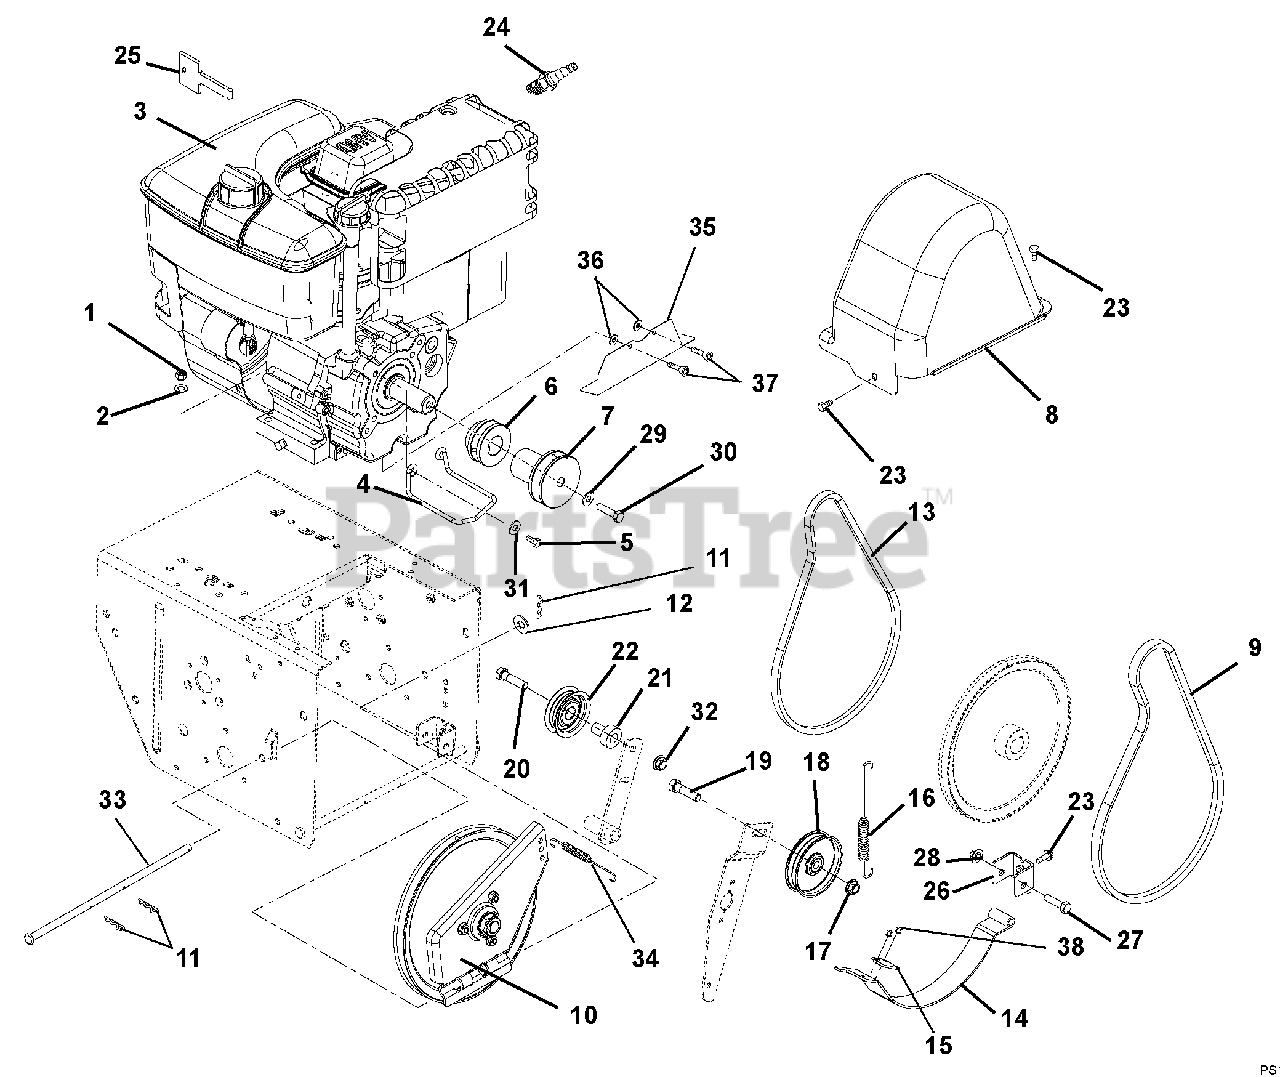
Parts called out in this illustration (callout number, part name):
1	Nut, Hex .31-18
2	Washer, Lock .312 x .097
3	Engine, 9HP Tecumseh OH318EA - 222719E
4	Belt Finger
5	Bolt, Hex .31-24 x .75 Grade 5
6	Sheave, Drive
7	Sheave, Attachment
8	Cover, Belt
9	V-Belt 4L
10	Plate, Swing Assembly
10	Plate, Deep Swing Assembly
11	Hair Pin
12	Washer, Flat Steel .406 x .812 x .065
13	V-Belt,Traction Drive
13	V-Belt,Traction Drive 3L
14	Arm, Brake Attachment
16	Spring, Tension
17	Nut, Locking Top Flange .38-16
18	Idler, Flat 3.00
19	Bolt, Hex .38-16 x 1.50 Grade 5
20	Bolt, Hex .31-18 x 1.25 Grade 5
21	Spacer, Bearing
22	Idler
23	Screw, Tapping .25-20 x .50 Hex Washer Head Thread Rolling
24	Plug, Spark
25	Key, Push/Pull Tecumseh
26	Pivot, Brake
27	Bolt, Hex .31-18 x 2.00 Grade 5
28	Nut, Locking-Top-Flange .31-18
29	Washer, Locking .38 x .094
30	Bolt, Hex .38-24 x 2.0
31	Washer, Locking .312 x .097 Heavy
32	Nut, Locking-Top-Flange .31-18
33	Rod, Pivot
34	Spring, Tension
35	Baffle, Engine (Serial No. 553 and up)
36	Washer, Flat-Steel .536 x 1.07 x .109 (Serial No. 553 and up)
37	Screw, Machine .31-24 x .75 EP80 (Serial No. 553 and up)
38	Rivet, Pop .187
